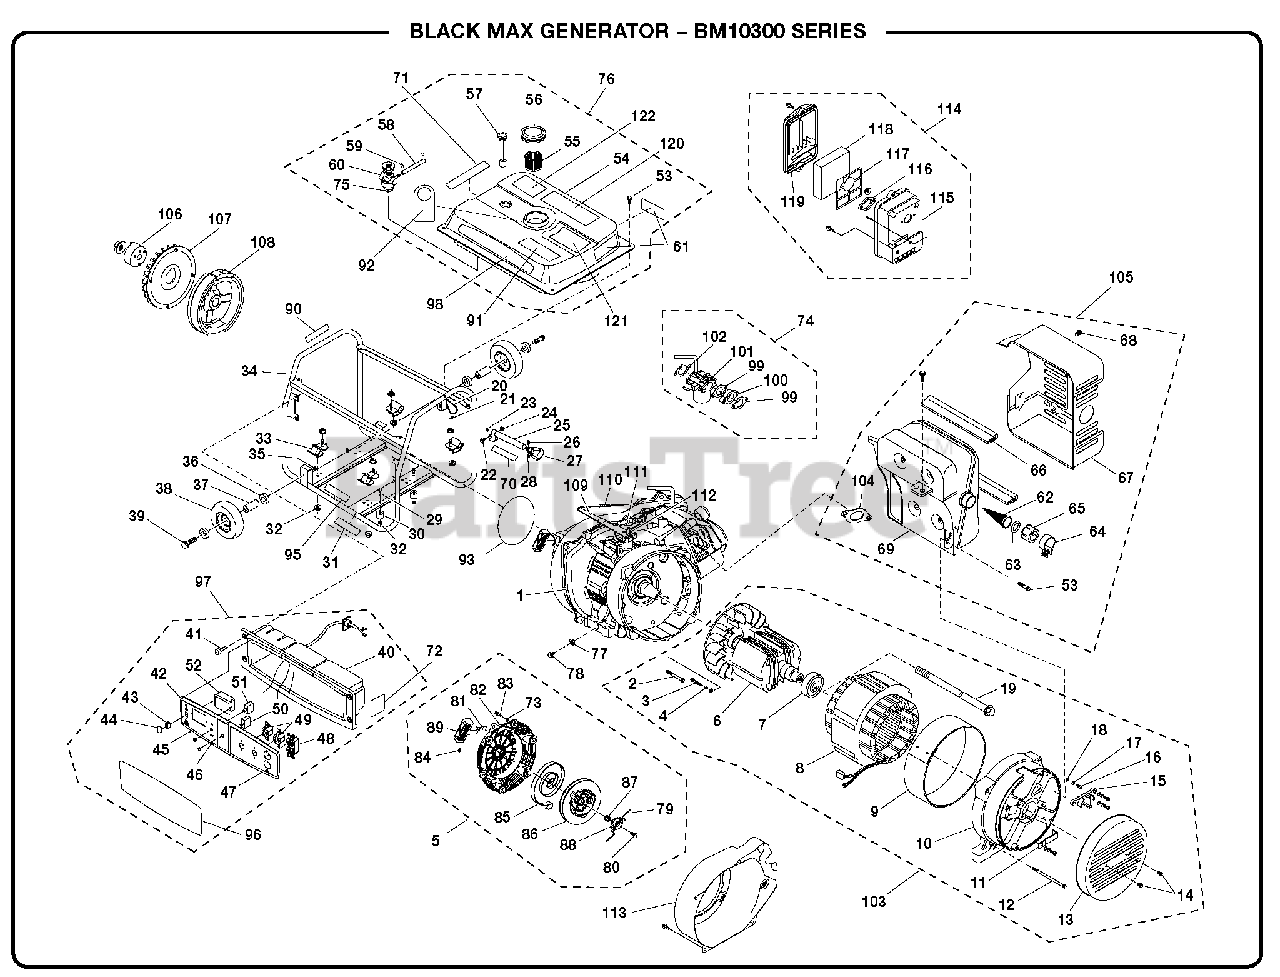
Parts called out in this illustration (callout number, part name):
1	Engine SPE195 (Incl. Key Nos. 148, 84, 125, 85)
2	Bolt (M8 x 35 mm)
3	Bolt (M6 x 12 mm)
4	Washer (M6)
5	Recoil Stator Assembly (Incl. Key Nos. 83, 90-100)
6	Rotor Assembly
8	Stator Assembly
9	Stator Cover
10	Rear Frame
11	Wire Compressing Plate
12	Bolt (M6 x 103 mm)
13	Rear End Cover
14	Bolt (M6 x 10 mm)
15	Wire Rack
17	Washer (M5)
18	Oil Filler Cap
22	Bolt (M8 x 40 mm)
23	Handle Stem Head
24	Lock Nut (M8)
26	Square Bolt
30	Alternator Vibration Absorber
31	Combustion Warning Label
33	Engine Vibration Absorber
35	Lock Nut (M10 x 1.25 in.)
36	Wheel Bush
37	Axis Cover
39	Bolt (M10 x 75 mm)
40	Control Box
41	Screw (M6 x 14 mm)
42	Control Panel
43	Choke Switch
44	Switch Jacket
45	Bolt (M3.5 x 9 mm)
46	Bolt (M3.9 x 9 mm)
47	Bolt (M4 x 8 mm)
48	120 V 20 Amp Receptacle
49	120 V 30 Amp Receptacle
50	AC Circuit Breaker (20A)
51	AC Circuit Breaker (30A)
52	4-in-1 Digital Meter
53	Bolt (M6 x 12 mm)
54	Fuel Tank
55	Fuel Filter
56	Fuel Tank Cap
57	Fuel Meter
58	Fuel Hose
59	Fuel Hose Clip
60	Fuel Cock
61	Hot Surface Label
62	Muffler Screen
65	Muffler Screen Cover
66	Shockproof Bar
67	Muffler Cover
68	Bolt (M6 x 10 mm)
70	Locking Pin Label
71	Start Guide Label
72	Ground Label
73	Bushing Block
74	Carburetor Assembly (Incl. Key Nos. 110-113)
76	Fuel Tank Assembly (Incl. Key Nos. 54-60, 86)
77	Oil Filler Seal
78	Drain Plug (M10 x 1.25-16)
82	Starter Case
83	Screw (M6 x 12 mm)
84	Rope Clip
85	Starter Spring
86	Drum Sheave
88	Pawl Guide
89	Starter Handle
90	Fire Danger Label
91	Ground Warning Label
92	Oil Hang Tag
93	Engine Shround Logo
94	Choke Label
95	Lubricant Label
96	Control Panel Label
97	Control Panel Assembly (Incl. Key Nos. 40-52, 135, 142)
98	Logo Label
101	Carburetor
103	Alternator Assembly (Incl. Key Nos. 3, 4, 6-17, 19)
104	Exhaust Gasket
105	Muffler Assembly (Incl. Key Nos. 53, 62-69, 115)
106	Starting Hub
109	Governor Arm
111	Carburetor Spring
114	Air Cleaner Assembly (Incl. Key Nos. 126-130)
115	Air Filter Case
117	Element Fitting Plate
118	Air Filter Element
119	Air Filter Cover
120	Warning Label
121	CPSC Label (English)
122	CPSC Label (FR/SP)
